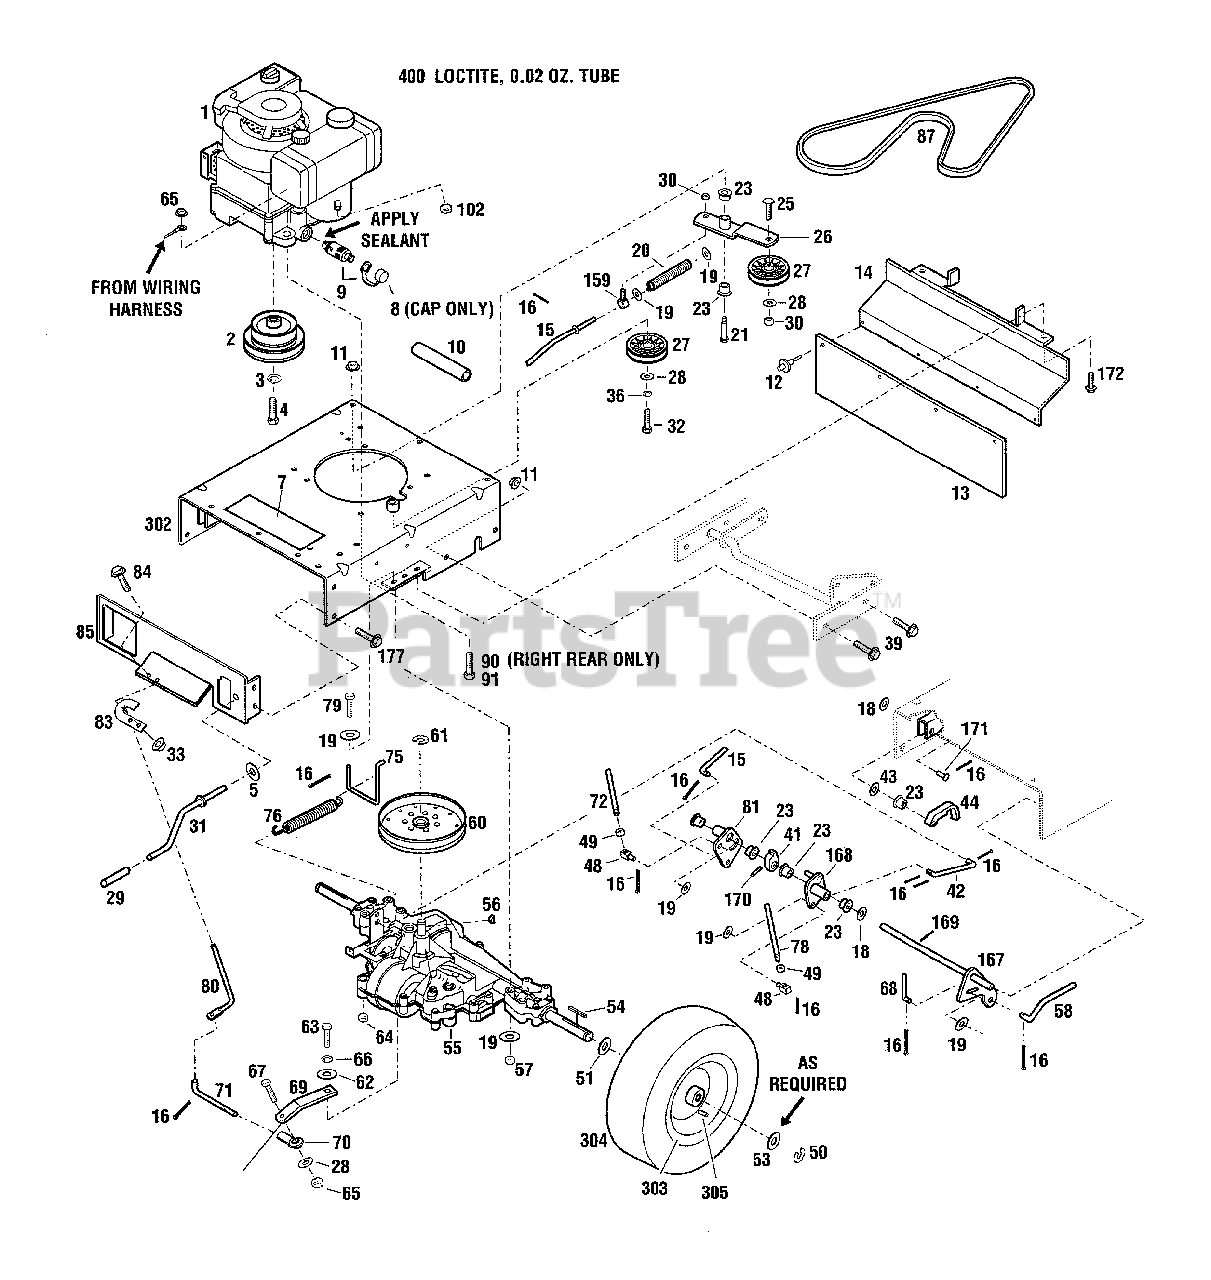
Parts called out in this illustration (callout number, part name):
1	Engine
2	Engine Pulley
3	Lock Washer, 7/16
4	Bolt, 7/16-20 x 1-3/4
5	Washer, Nylon
7	Warning Decal
8	Oil Valve Cap
9	Oil Valve
10	Oil Drain Hose
11	Flange Locknut, 3/8-16
12	Pop Rivet, 3/16
14	Flap Bracket
15	Lower Transmission Rod
16	Cotter Pin, 3/32 x 5/8
18	Flat Washer, 1/2
19	Flat Washer, 5/16
20	Compression Spring
21	Shoulder Bolt
23	Nyliner, 1/2
25	Carriage Bolt, 3/8-16 x 1-3/4
26	Idler Arm
27	Idler Pulley
28	Flat Washer, 3/8
29	Plastic Grip
30	Top Locknut, 3/8-16
31	Lift Crank Assembly
32	Bolt, 3/8-16 x 1-3/4
33	Flange Locknut, 1/4-20
36	Lock Washer, 3/8
39	Flange Lock Screw, 3/8-16 x 1
41	Interlock Cam
42	Lower Brake Rod
43	Washer, Flat 1/2
44	Interlock Latch
48	Swivel Block
49	Jam Nut, 5/16-18
50	Retaining Ring
51	Flat Washer
53	Special Washer
54	Square Key, 3/16 x 2-1/2
56	Woodruff Key, 3/16 x 3/4
57	Top Locknut, 5/16-18
58	Lower Blade Rod
60	Transaxle Pulley
61	Retaining Ring
62	Flat Washer, 1/4
63	Screw, 1/4-28 x 3/4
64	Flange Locknut, 5/16-18
65	Locknut, 3/8-16
66	Lock Washer, 1/4
67	Screw, 3/8 x 1-1/4
68	Upper Blade Rod
69	Transmission Arm
70	Ball Joint
71	Shift Link Rod
72	Upper Transmission Rod
75	Spring Attachment Rod
76	Extension Spring
78	Upper Brake Rod
79	Screw, 5/16-18 x 2-3/4
80	Shift Rod
81	Clutch Arm Pivot
83	Shift Rod Bracket
84	Flange Lock Screw, 1/4-20 x 1/2
90	Thread Forming Screw, 3/8-16 x 1-1/2
91	Thread Forming Screw, 3/8-16 x 1
102	Hex Nut, 1/4-20
159	Eye Bolt
167	Pivot Shaft Assembly
168	Brake Arm
169	Cotter Pin
170	Drive Pin, 5/32 x 1
171	Clevis Pin, 1/2 x 1-1/4
172	Screw, 5/16-18 x 3/4
177	Flange Screw, 5/16-18 x 3/4
302	Frame Weldment Ass'y
303	Wheel Rim
304	Tire
305	Valve Stem
400	Loctite 242, 0.02 oz. Tube
